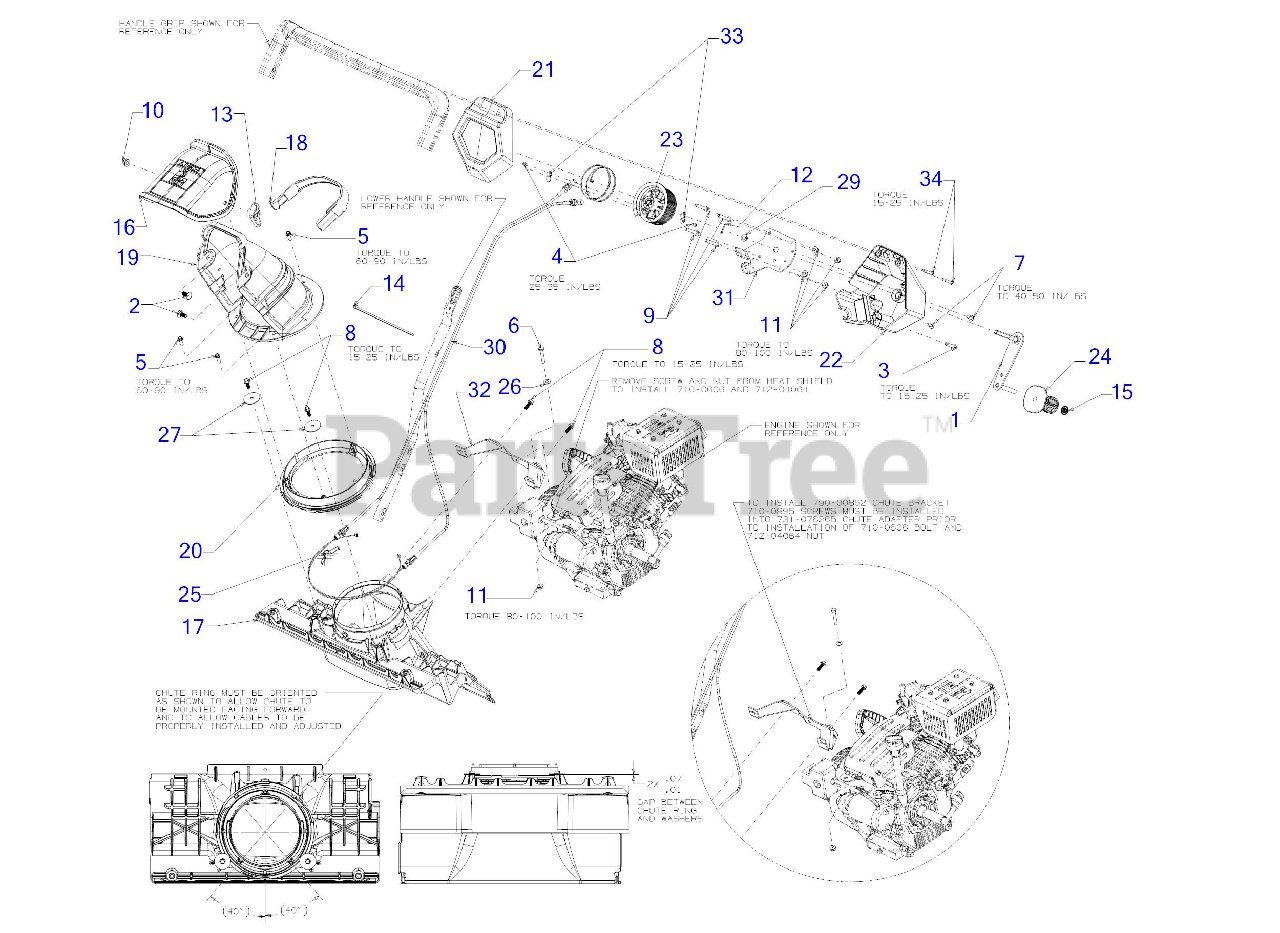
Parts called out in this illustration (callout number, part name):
2	CARRIAGE BOLT 5/16-18 x .75
3	SCREW 1/4-15 x 1.250
4	SCREW 8-16 X .375" T20
5	SCREW 1/4 x .750
6	SCREW 1/4-20 x 1.50 GR.5
7	SCREW M6-1 x .625
8	SCREW 1/4-15 x .750
9	CABLE KEEPER
10	FLANGE LOCK NUT 5/16-18
11	FLANGE LOCK NUT
12	COTTER PIN 3/32
13	WING KNOB 5/16-18
14	7" CABLE TIE
15	PUSH NUT
16	UPPER CHUTE
17	CHUTE ADAPTER
18	CHUTE PLUG
19	LOWER CHUTE 6.5
20	RING: CHUTE CABLE CONTROL
21	UPPER HANDLE PANEL
22	LOWER CONTROL HOUSING
23	CHUTE CABLE SPOOL
26	FLAT WASHER
27	FLAT WASHER
29	FLANGE BEARING
30	CHUTE ROTATION CABLE
31	CHUTE ROTATION BRACKET
32	CHUTE CRANK BRACKET
33	CABLE CLIP
34	SCREW
